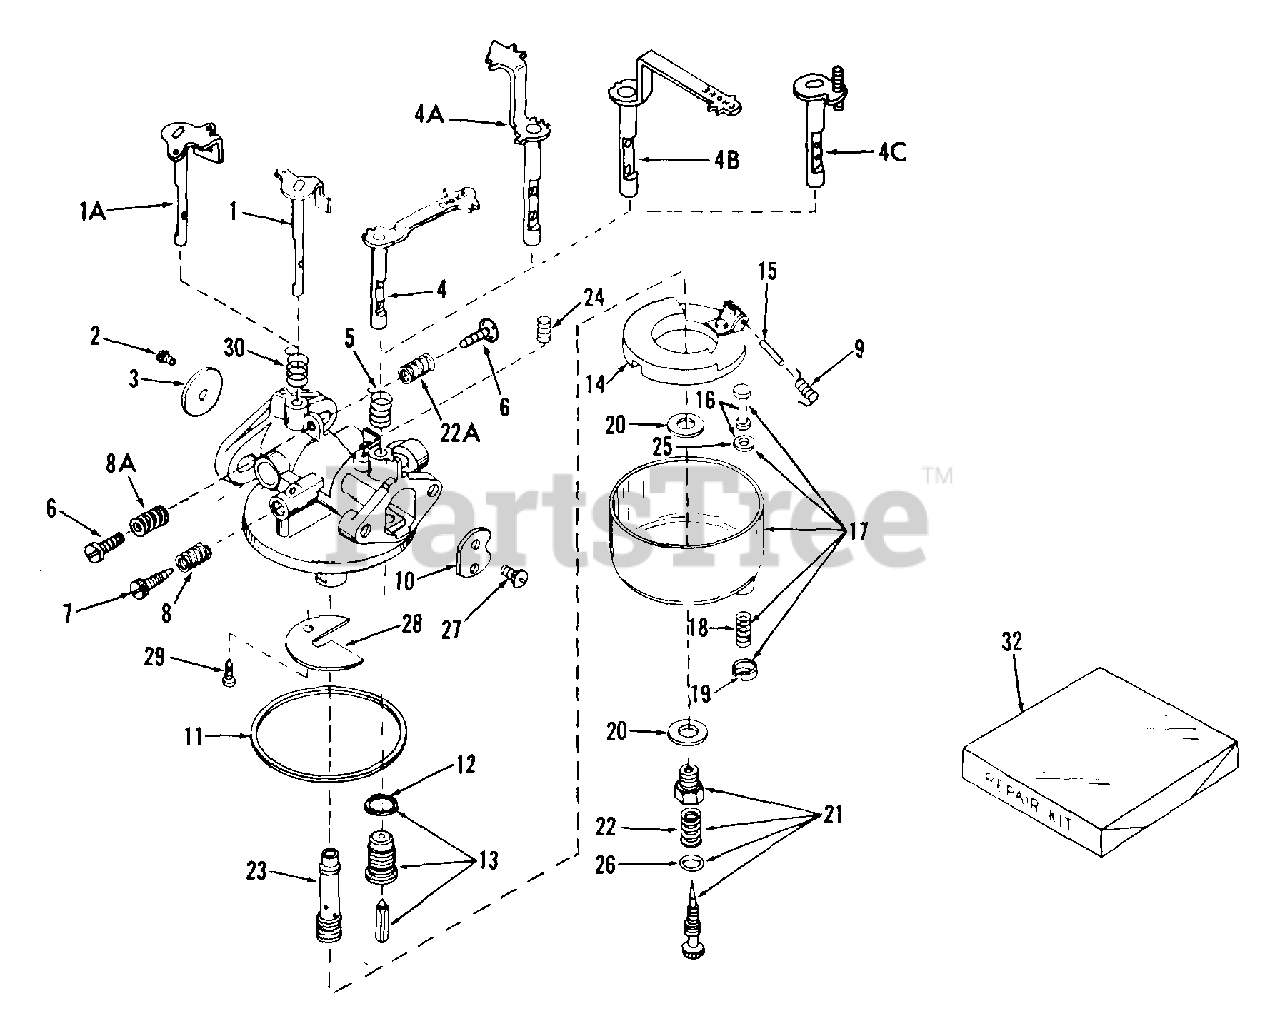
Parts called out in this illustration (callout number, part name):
1A	"Shaft & Lever Assy., Throttle
2	Screw, Sems, 6-32 x 3/16
3	Shatter, Throttle
4	Shaft & Lever Assy., Choke
6	Screw, Throttle adjusting
7	Needle, Idle adjusting
8	Spring, Adjusting needle
8A	Spring, Adjusting needle
10	Shutter, Choke
11	Gasket, Bowl-to-body
12	Gasket, Valve seat
13	Valve, Seat & Gasket Assy.
15	Shaft, Float
16	Stem Assy., Bowl drain
17	Bowl & Drain Assy.
18	Spring, Bowl drain
19	Retainer, Bowl drain stem
20	Gasket, Bowl-to-body
21	Needle Assy., Power adjusting
22	Spring, Adjusting needle
23	Nozzle, Main
24	Spring, Choke stop
25	Gasket, Drain stem
26	"O" Ring
27	Screw, Sems
28	Baffle, Carburetor
29	Screw, Baffle
30	Spring, Throttle return
32	Repair Kit
